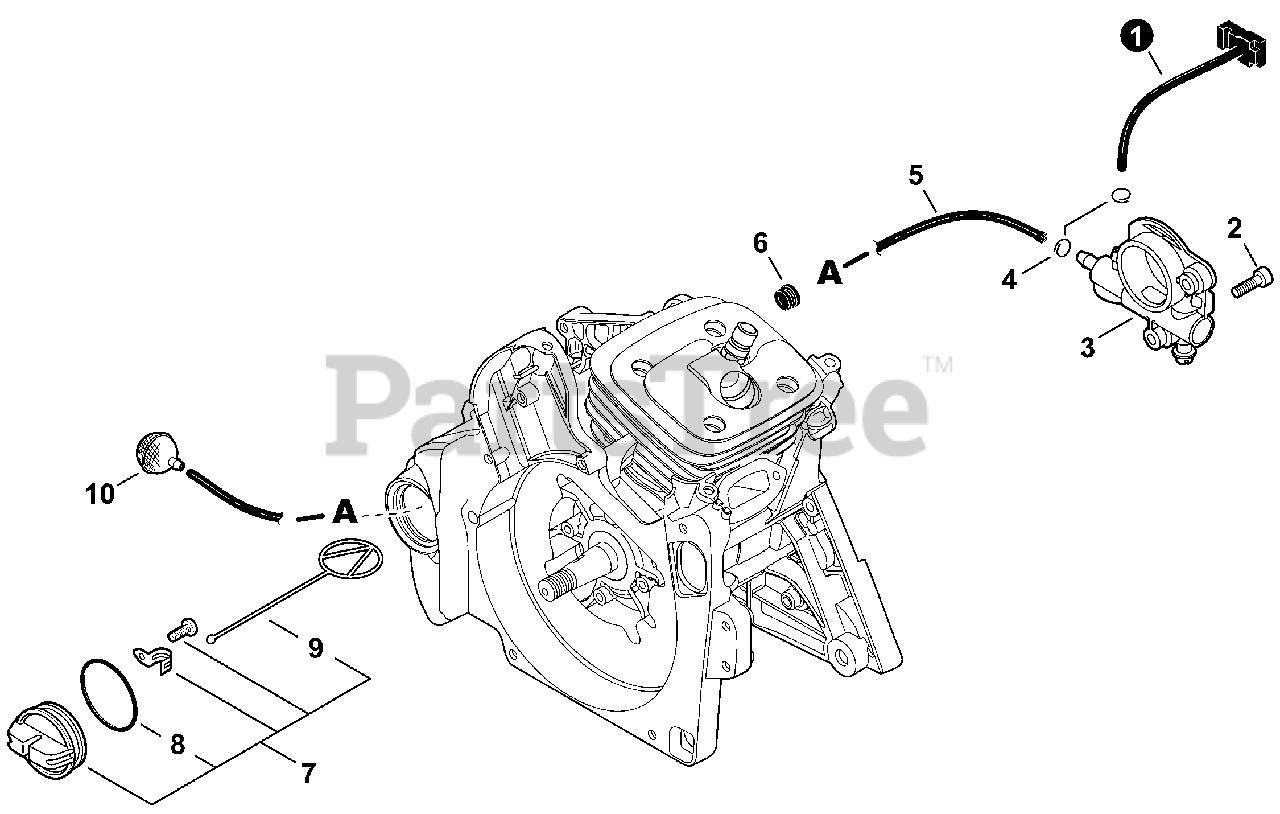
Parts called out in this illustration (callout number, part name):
1	PIPE, OIL
2	BOLT, TORX 4×12
3	AUTO-OILER ASSY
4	CLIP Ø6
5	PIPE, FUEL 3×6×210 BLACK
6	GROMMET
7	CAP ASSY, OIL
8	O-RING 28
9	CONNECTOR, CAP L= 60 MM
10	FILTER, OIL
